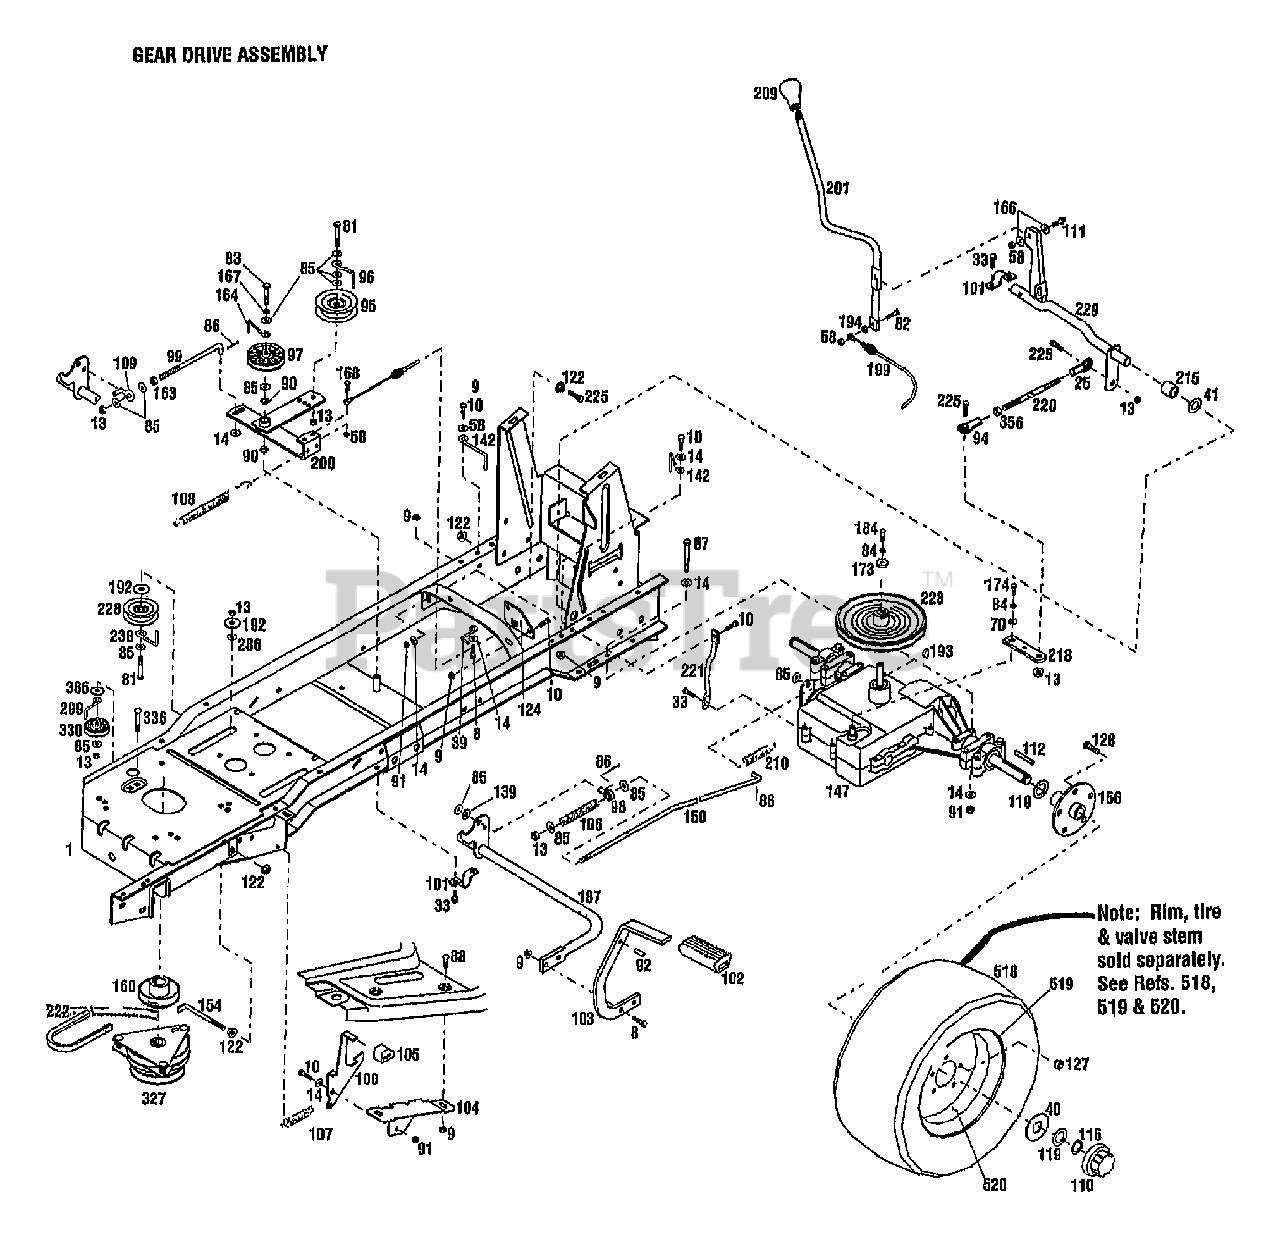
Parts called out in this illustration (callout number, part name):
8	SCR-HH 5/16-18X1.0 G5 ZP
9	NUT-HFLK 5/16-18 ZP
10	SCR-HHC 5/16-18X.75 GR 5 ZP
13	NUT-LOCK 3/8-16
14	WASHER-FLAT 5/16 SAE
25	JOINT-BALL
33	SCR-HFLK 5/16-18X.75
39	GUIDE-BELT
40	WASHER-SPEC .75X2.50
41	WASHER-THRUST
58	NUT-HT LK 1/4-20
70	WASHER-FLAT 1/4 SAE
81	SCR-HH 3/8-16X2.0 G5 ZP
82	SCR-HH 1/4-20X1.0
83	SCR-HH 3/8-16X1.75 G5 ZP
84	WASHER-LK .25 ZP
85	WASHER-FLAT 3/8 SAE
86	PIN-COTTER .09X.75 ZP
87	SCR-HH 5/16-18X2.75 G5 ZP
88	SCR-CARR 5/16-18X.62 G2 ZP
90	BUSHING-.5X.5 NYLON FLNG
91	NUT-TOP/LK 5/16-18 ZP
92	PIN-.312X.75
94	JOINT-BALL
96	GUIDE-BELT
97	PULLEY-IDLER
98	SWIVEL
99	ROD-CLUTCH
100	LATCH-BRAKE CLUTCH USE1771514
101	CLIP-CLAMP .75 ID
102	PAD-FOOT PEDAL
103	PEDAL-BRAKE
104	BRKT-BRAKE LOCK
105	PAD-BRAKE
106	SPRING-COMPRESSION
107	SPRING-EXTENSION
108	SPRING-EXTENSION
109	ROD-PIVOT
110	CAP-HUB
111	SCR-HFLK 1/4-20X1.00
112	KEY-.25 SQ X 2.0
116	RING-RETAINING
119	WASHER-SPEC
122	NUT-HFLK 3/8-16 ZP
124	SUPPORT-CABLE
127	NUT-LUG 7/16-20
128	BOLT-WHEEL
139	WASHER-.376 DIA
142	GUIDE-BELT
147	TRANSAXLE
154	RETAINER-CLUTCH
160	PULLEY-ENGINE
163	NUT-HEX 3/8-16 ZP
164	GUIDE-BELT
166	WASHER-FLAT 1.25X.28X.062 ZP
167	WASHER-LK .375 @ DEPL
168	SCR-HH 1/4-20X.75 G5 ZP
173	WASHER-.865X.281X.1793
174	SCR-HHC 1.4-28 X .50
184	SCR-HH 1/4-20X1.25
187	ASSM-BRAKE PEDAL
192	WASHER-1.12X.378X.125
193	KEY-WOODRUFF .188X.75
194	NUT-HEX 1/4-20 ZP
199	CABLE-SHIFT
200	PLATE-IDLER
201	ARM-SHIFT
210	SPRING-EXTENSION
215	SPACER
218	ARM-TRANSMISSION
220	ROD-ADJUSTING
221	SUPPORT-TRANSMISSION
222	BELT-V
223	PULLEY-TRANSMISSION
225	SCR-HH 3/8-16X1.25
228	IDLER-SHEAVE 3" X 1"
229	SHAFT-PIVOT
238	GUIDE-BELT
286	WASHER-.75X.406X.092
299	GUIDE-BELT
327	CLUTCH-ELECTRIC
330	PULLEY-IDLER
336	BOLT-CARR
356	NUT-HEX/JAM 3/8-24 ZP
386	WASHER-1.06X.531X.1 ZP
519	RIM-WHEEL REAR
520	STEM-VALVE
